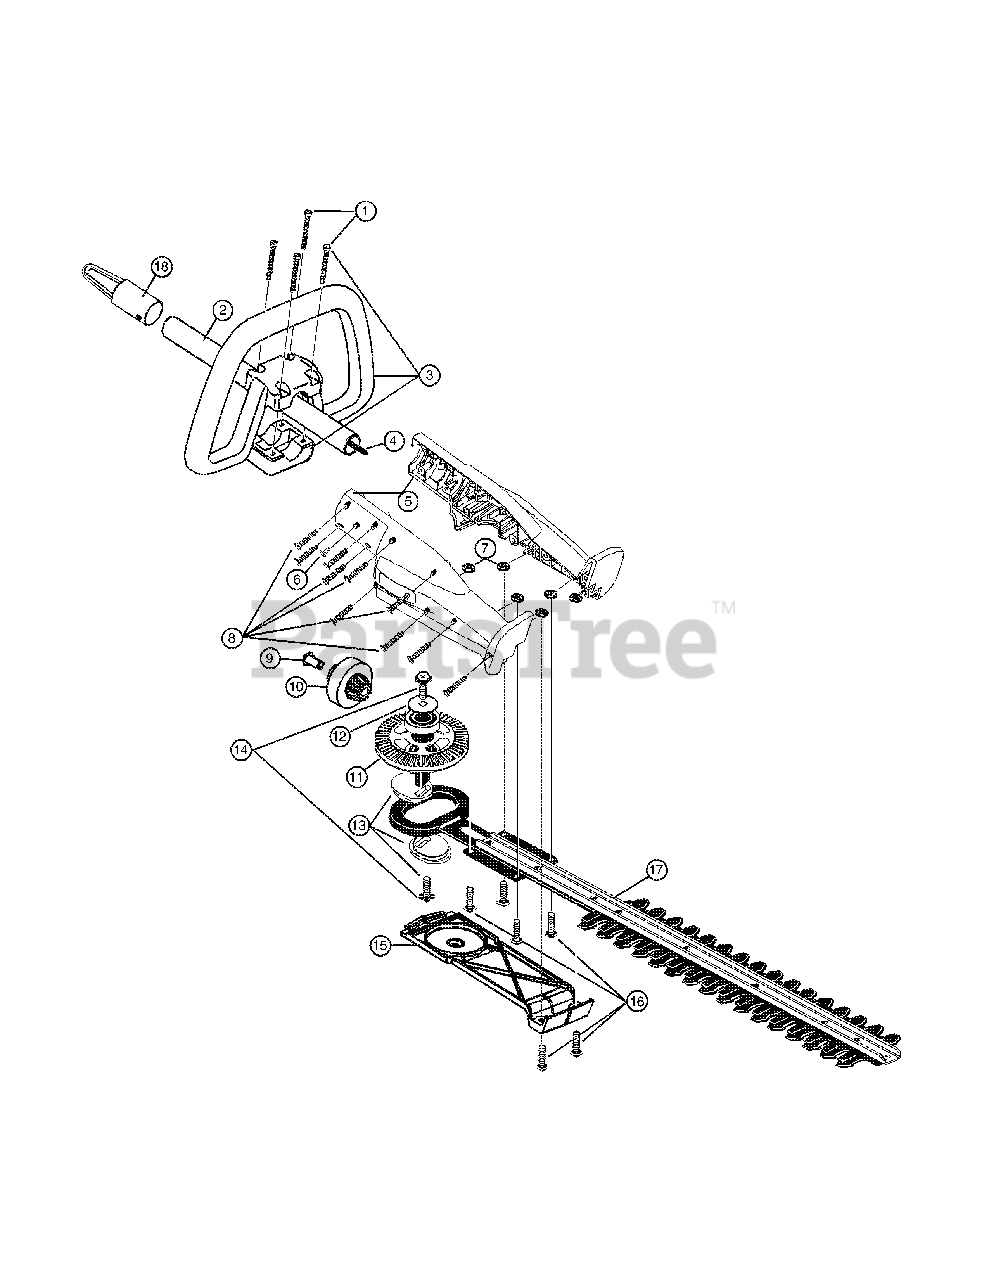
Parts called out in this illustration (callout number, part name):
2	Drive Shaft Housing Assembly
3	Loop Handle Assembly
4	Drive Shaft Assembly
5	Housing Set
6	Anti-Rotation Screw
8	Housing Screw
10	Pinion Gear
11	Bevel Gear Assembly(includes items 12-14)
13	Cam Assembly (includes 14)
15	Bottom Plate
17	Cutting Blade Assembly
18	Hanger
